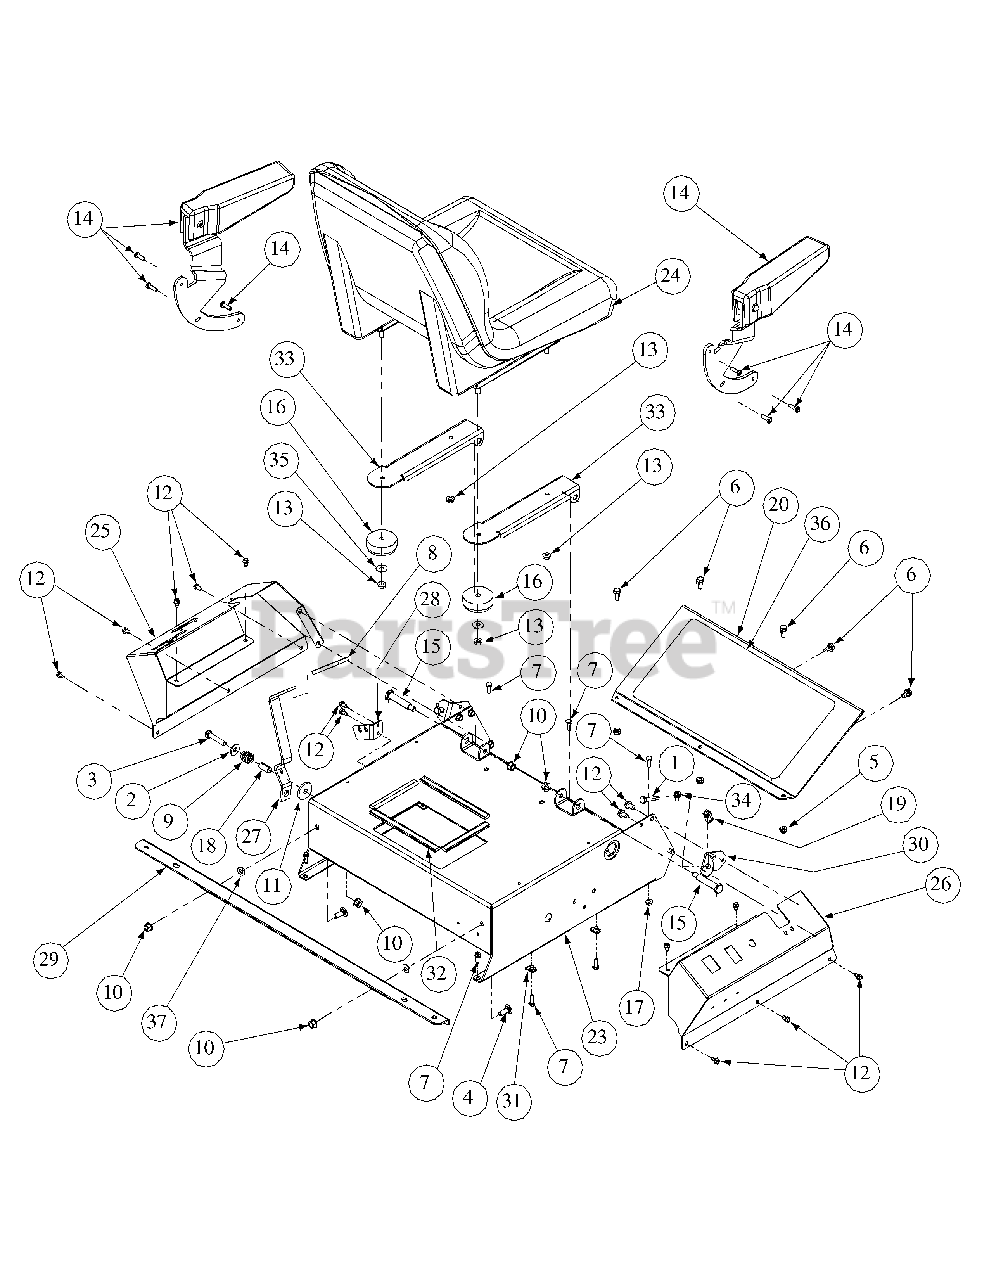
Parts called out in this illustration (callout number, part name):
1	Hex Cap Screw, 5/16-18 x 1-1/2
2	Idler Washer
3	Capscrew, 3/8-16 x 1-3/4
4	Carriage Bolt, 3/8-16
5	Nylock Nut, 5/16-18
6	Self Tapping Screw, 5/16-18 x 3/4
7	Self Tapping Screw, 1/4-20 x .75
8	Parking Brake Grip
9	Spring, .85 OD x 1 Lg
10	Hex Nut, 3/8-16 Flange Lock
11	Flat Washer, 1.25 x .411 x .100
12	Screw, 1/4-20 x 1/2
13	Hex Nut, 5/16-18 Flange Lock
14	Kit, Armrest
15	Shoulder Screw, 3/8-16, .5 x 2.345
16	Groment, 2.5 OD x 1.0 Lg
17	Hex Nut, 1/4-20 Flange Lock
18	Spacer, .375 x .50 x 1.02
19	U-Nut, 5/16-18
20	Foot Rest Bracket
23	Control Housing Weldment
24	Seat Adjust
25	Left Hand Control Console
26	Right Hand Control Console
27	Parking Brake Lever
28	Brake Cable Bracket
29	Front Tank Mounting Bracket
30	Lapbar Stop Bracket
31	U-Nut, 1/4-20
32	Battery Edge Trim
33	Seat Mounting Bracket
34	Hex Nut, 5/16-18
35	Washer, .325 x .930 x .045
36	Abrasive Foot Pad
37	Flat Washer, .406 ID x 1.0 OD x .105
